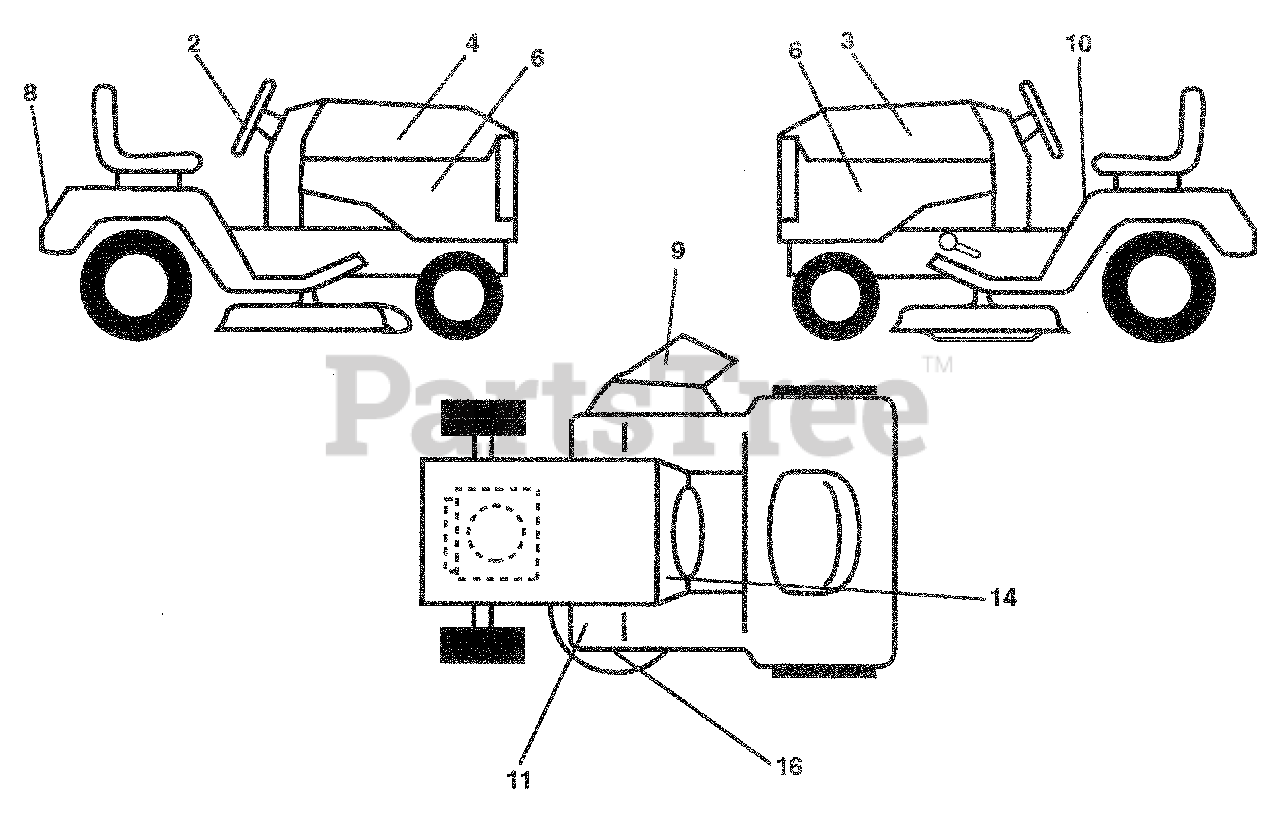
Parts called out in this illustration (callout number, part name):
2	Decal, Cap Steering
3	Decal, Hood LH
4	Decal, Hood RH
6	Decal, Panel Side
8	Decal, Fender
9	Decal, Danger Del.
10	Decal, Caution
11	Decal, Clutch/Brake
14	Decal, Operation Instruction
16	Decal, Rotating, Blades
